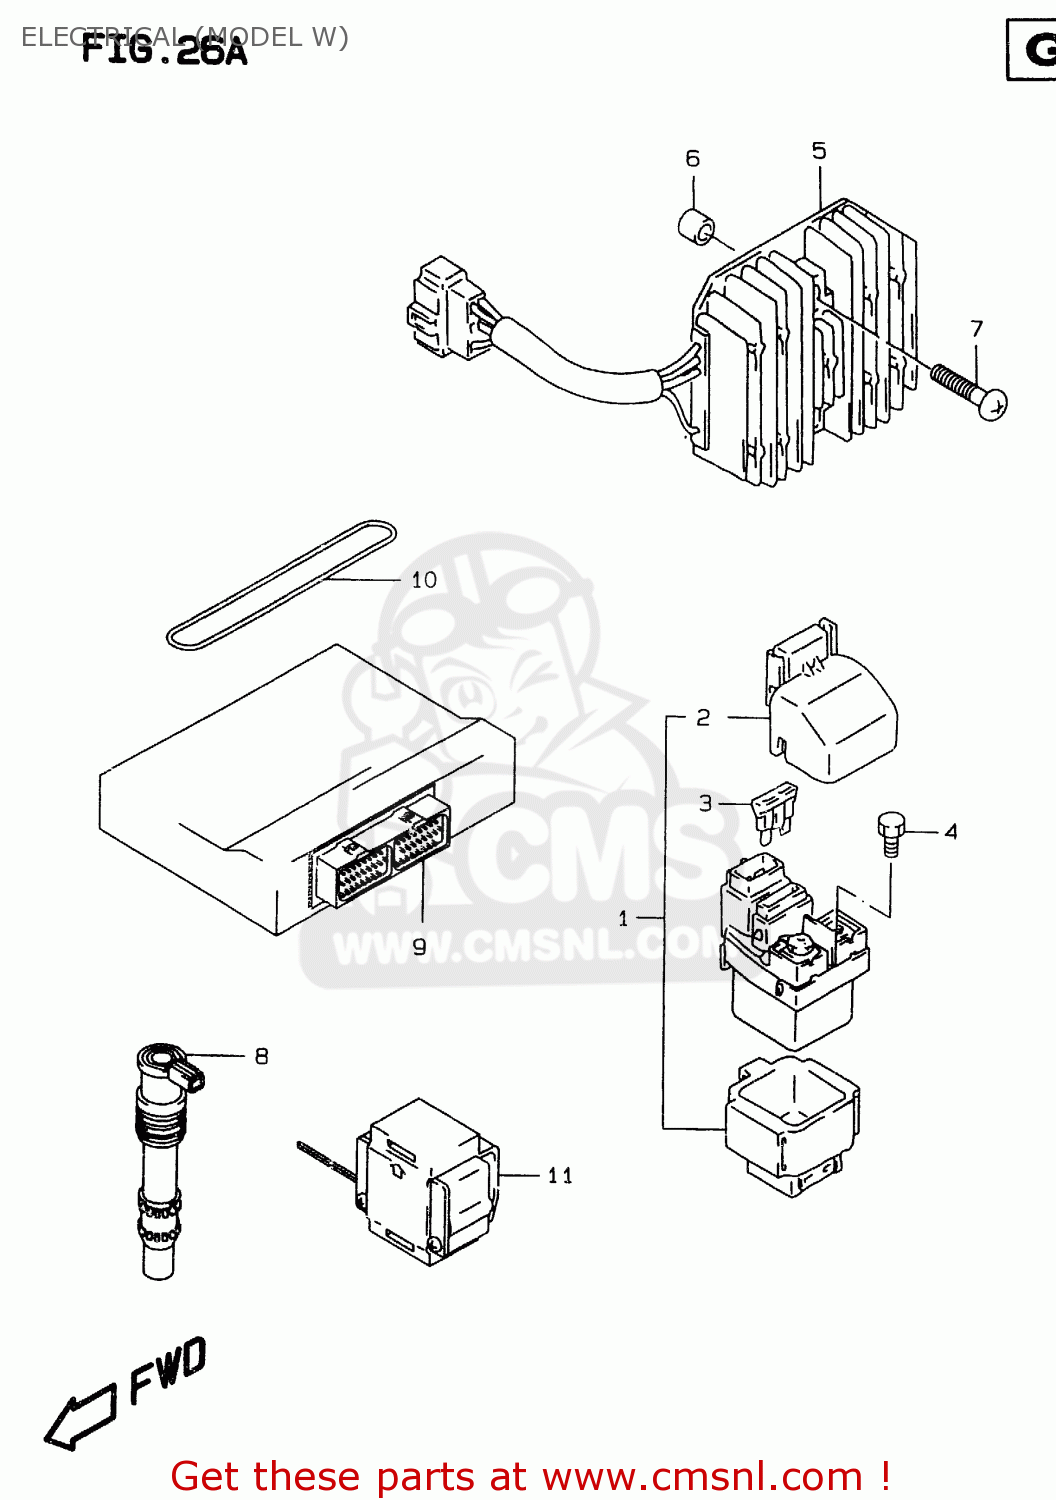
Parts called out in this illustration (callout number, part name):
1	RELAY ASSY,STARTING MOTOR
2	COVER,STARTER RELAY
3	FUSE(30A)
4	SCREW(6X8)
5	RECTIFIER ASSEMBLY
6	SPACER(6.5X10X7)
7	SCREW
8	COIL ASSY,IGNITION
9	CONTROL UNIT,EPI
10	BAND,BATTERY
11	SENSOR ASSY,FUEL CUT
